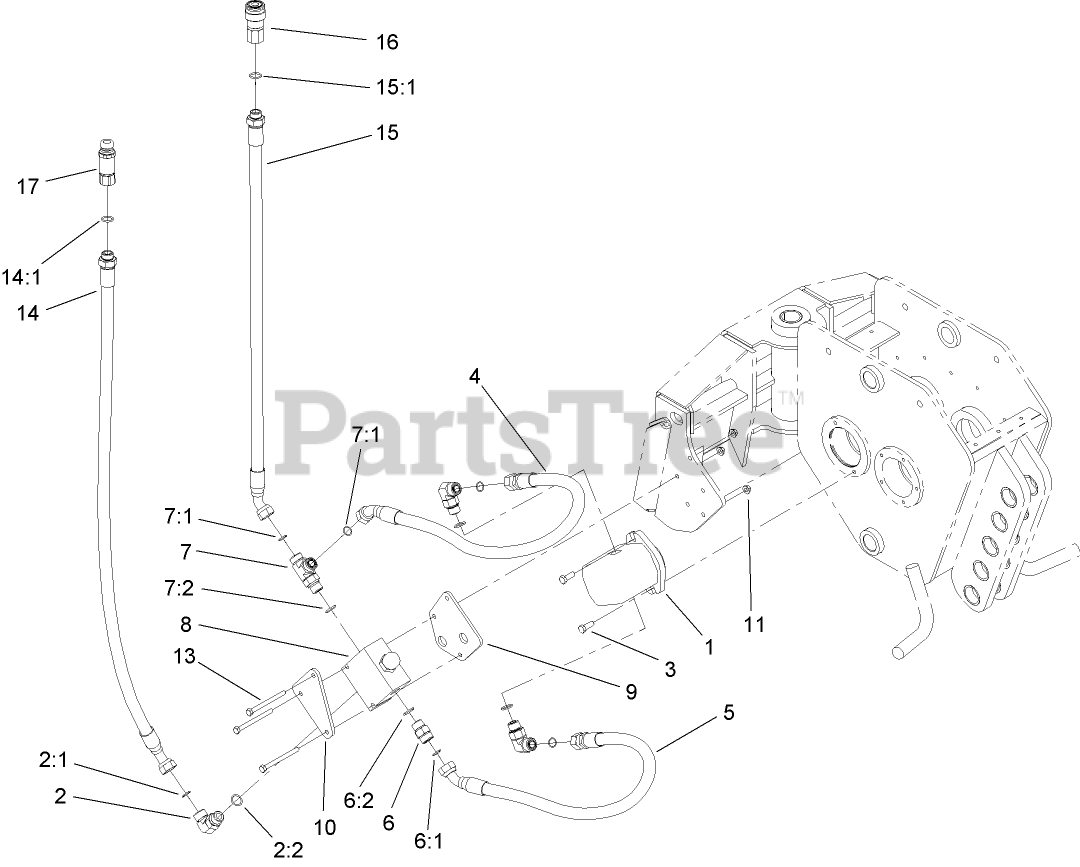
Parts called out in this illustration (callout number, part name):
1	MOTOR-HYD
2	FITTING-ELBOW-90
2:1	O-RING
2:2	O-RING
3	SCREW-HH
4	HYD HOSE ASM
5	HYD HOSE ASM
6	FITTING-STRAIGHT
6:1	O-RING
6:2	O-RING
7	FITTING-TEE
7:1	O-RING
7:2	O-RING
8	FLOW VALVE ASM
9	PLATE-SPACER, VALVE
10	PLATE-CLAMP
11	NUT-HF
13	SCREW
14	HYD HOSE ASM
14:1	O-RING
15	HYD HOSE ASM
15:1	O-RING
16	COUPLER-FACE, FLUSH
17	NIPPLE-CONNECT, PRESSURE
